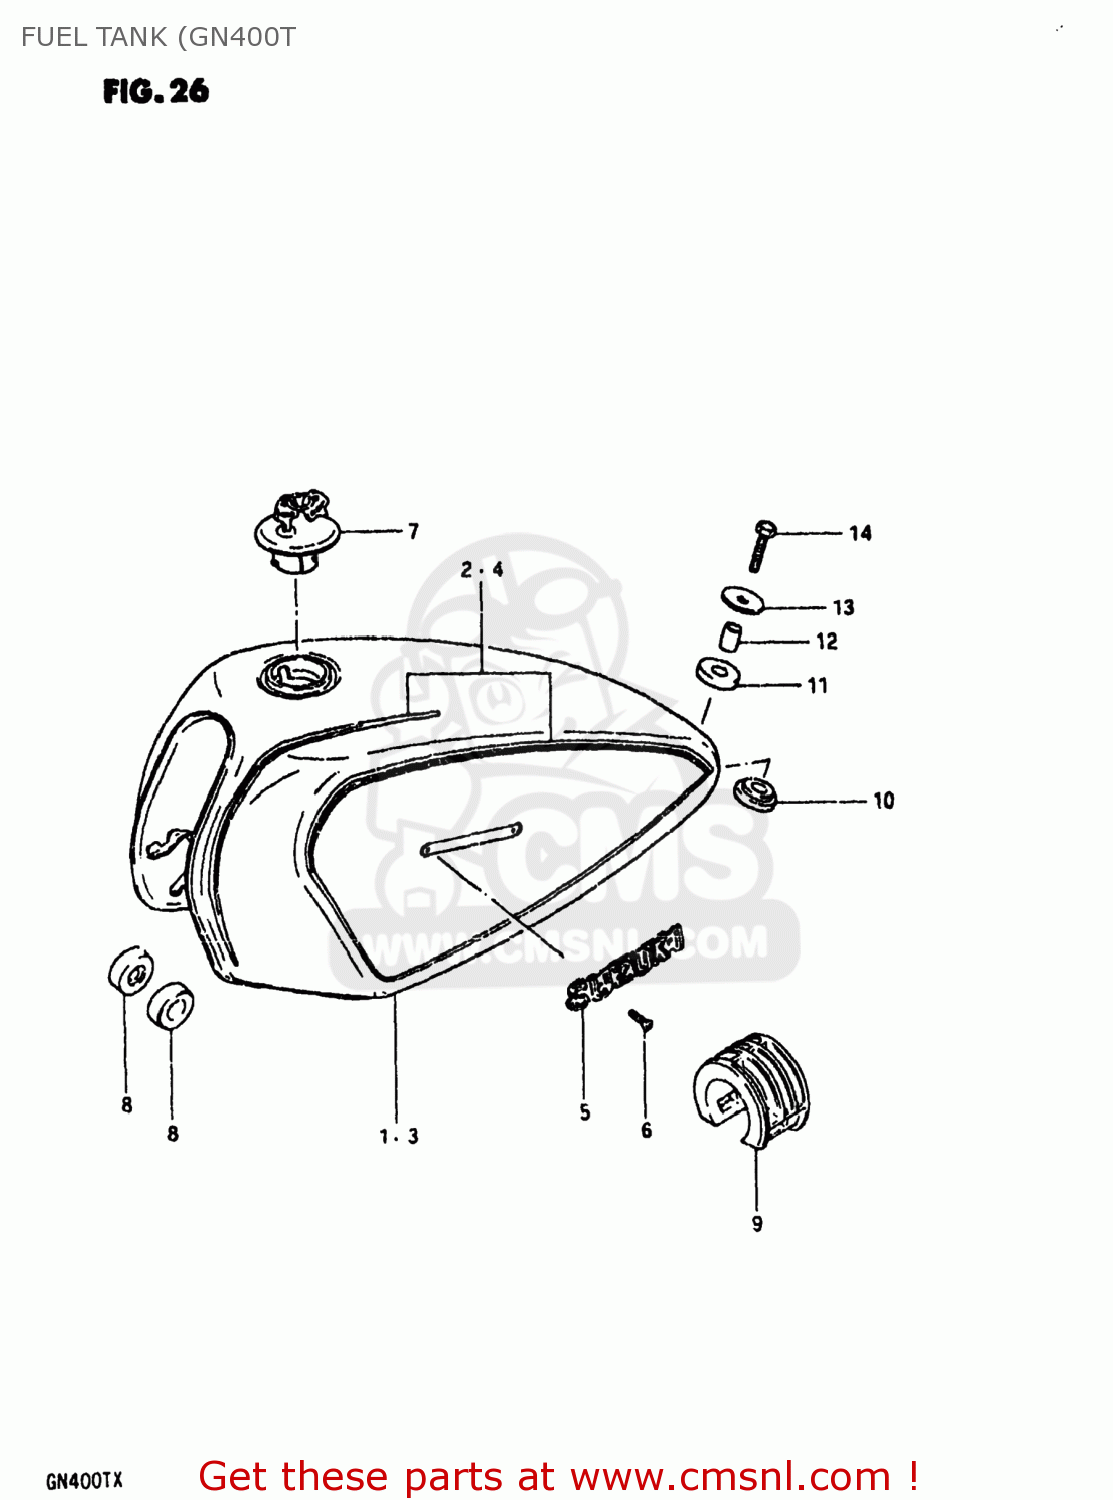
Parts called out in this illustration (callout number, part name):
1	TANK ASSEMBLY,FUEL
2	TAPE SET,FUEL TANK
3	TANK ASSEMBLY,FUEL
4	TAPE SET,FUEL TANK
5	EMBLEM,FUEL TANK
6	SCREW 3X6
7	CAP SET,FUEL TANK
8	CUSHION
9	CUSHION,FUEL TANK
10	CUSHION
11	CUSHION
12	SPACER (8.2X12X17)
13	WASHER (8.5X29X1.6)
14	BOLT (8X30)
